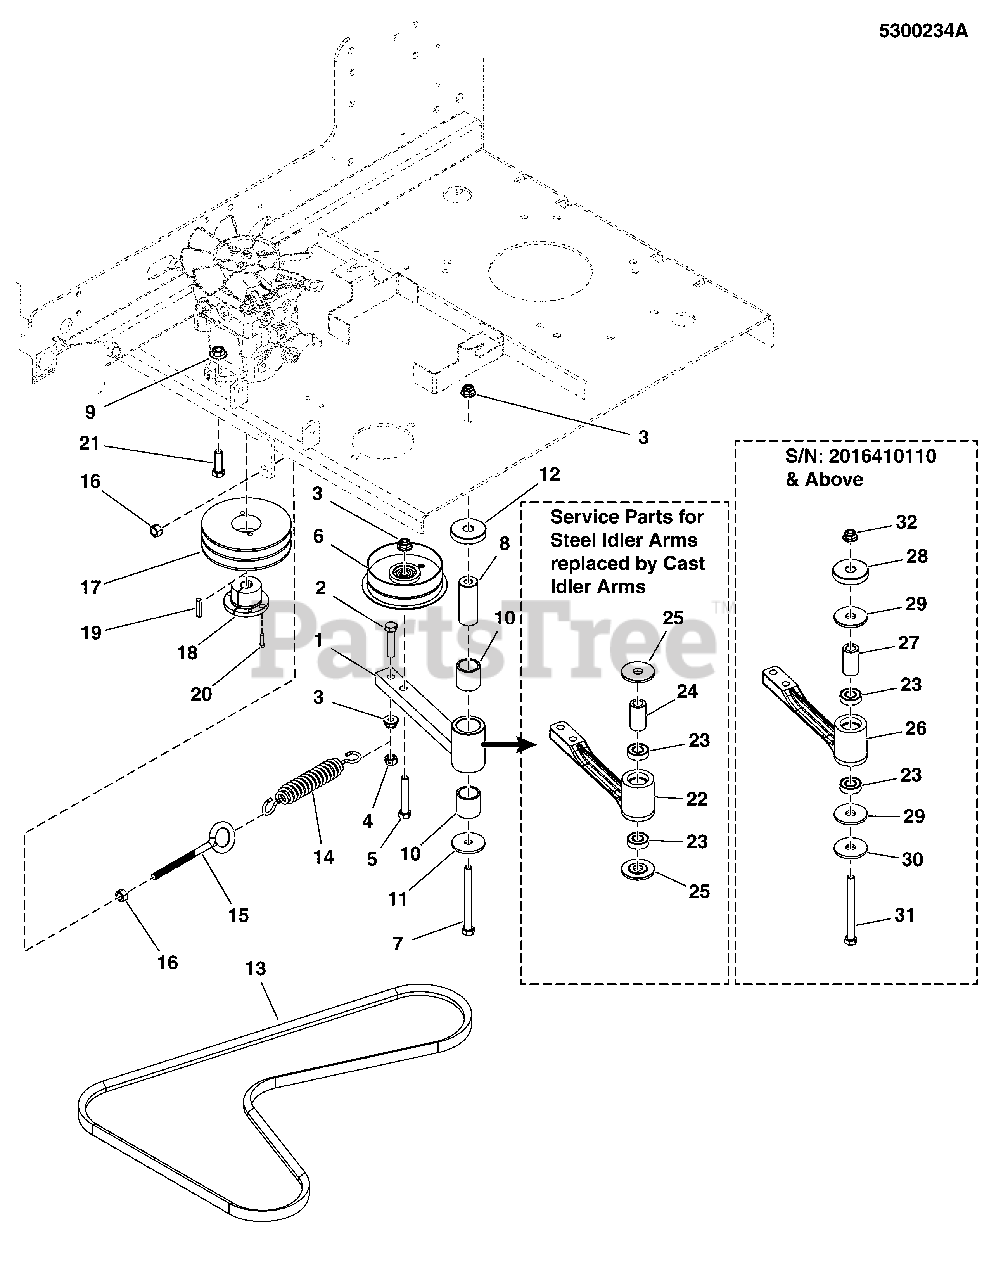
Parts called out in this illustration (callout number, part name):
2	BOLT, 3/8-16 X 1-3/4 GD5
3	NUT, 3/8-16 HEX NYLOCK FLANGE
4	NUT, 3/8-16 HEX SIDE LOCK
5	BOLT, 3/8-16 X 2-1/4 GD5 YZ
6	PULLEY, SINGLE FLANGED, 4"ODX3/8"ID
7	BOLT, 3/8-16 X 4 GD5 YZ
8	SPACER, .39 X 1.00 X 2.55, SS
9	NUT, 3/8-16 HEX SERRATED FLANGE
10	BUSHING, BRASS, 1.25X1X1.25
11	WASHER, .41 X 1.75 X .14
12	SPACER, .45 X 1.88 X .38
13	BELT, BANDED A-SEC,64.76EL,POLY,RAW EDGE
14	SPRING-EXT, 1.04 ODX6.935LGX.148WR, BLK
15	EYE BOLT, 3/8-16 X 6, 3THRD, 1EYE, CZ
16	NUT, 3/8-16 HEX
17	PULLEY, PUMP DRIVE
18	BUSHING, TAPERED HUB
19	KEY, 5MM SQ. W/ RADIUS
20	BOLT, 1/4-20 X 1", GD
21	BOLT, 3/8-16 X 1-1/4" GD5
22	ASSM, IDLER ARM, PUMP DRIVE, 3/8ID, CAST
23	BEARING, BALL, AXLE
24	SPACER, .39 X .88 X 1.53, CZ
25	SPACER, IDLER ARM, T-STYLE, CZ
26	ASSM, IDLER ARM, PUMP DRIVE, 1/2ID, CAST
27	SPACER, .52 X .84 X 1.53, PM
28	SPACER, .52 X 1.88 X .38
29	SPACER, IDLER ARM, 1/2, PM
30	WASHER, .52 X 1.75 X .14, CZ
31	BOLT, 1/2-13 X 4 GD5 YZ
32	NUT, 1/2-13 HEX NYLOCK FLANGE
